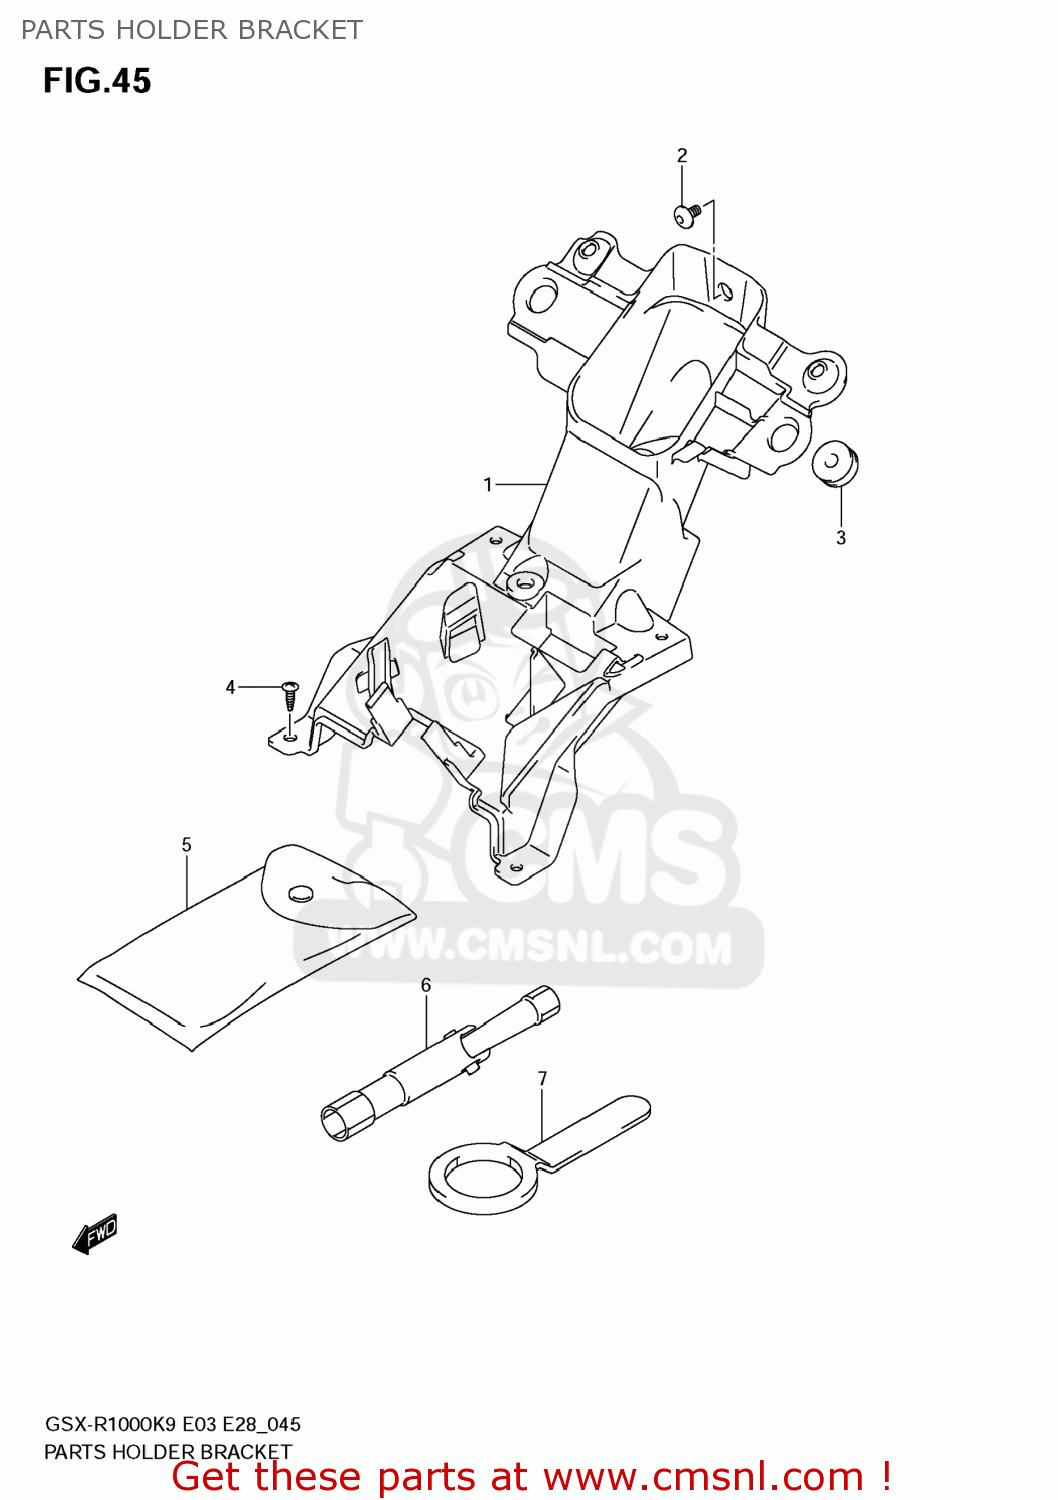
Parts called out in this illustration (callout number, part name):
1	BRACKET,ELECTRIC PARTS HOLDER
2	SCREW(6X12)
3	CUSHION
4	SCREW
5	TOOL ASSY
6	SPARK PLUG WRENCH
7	RING SPANNER(36)
